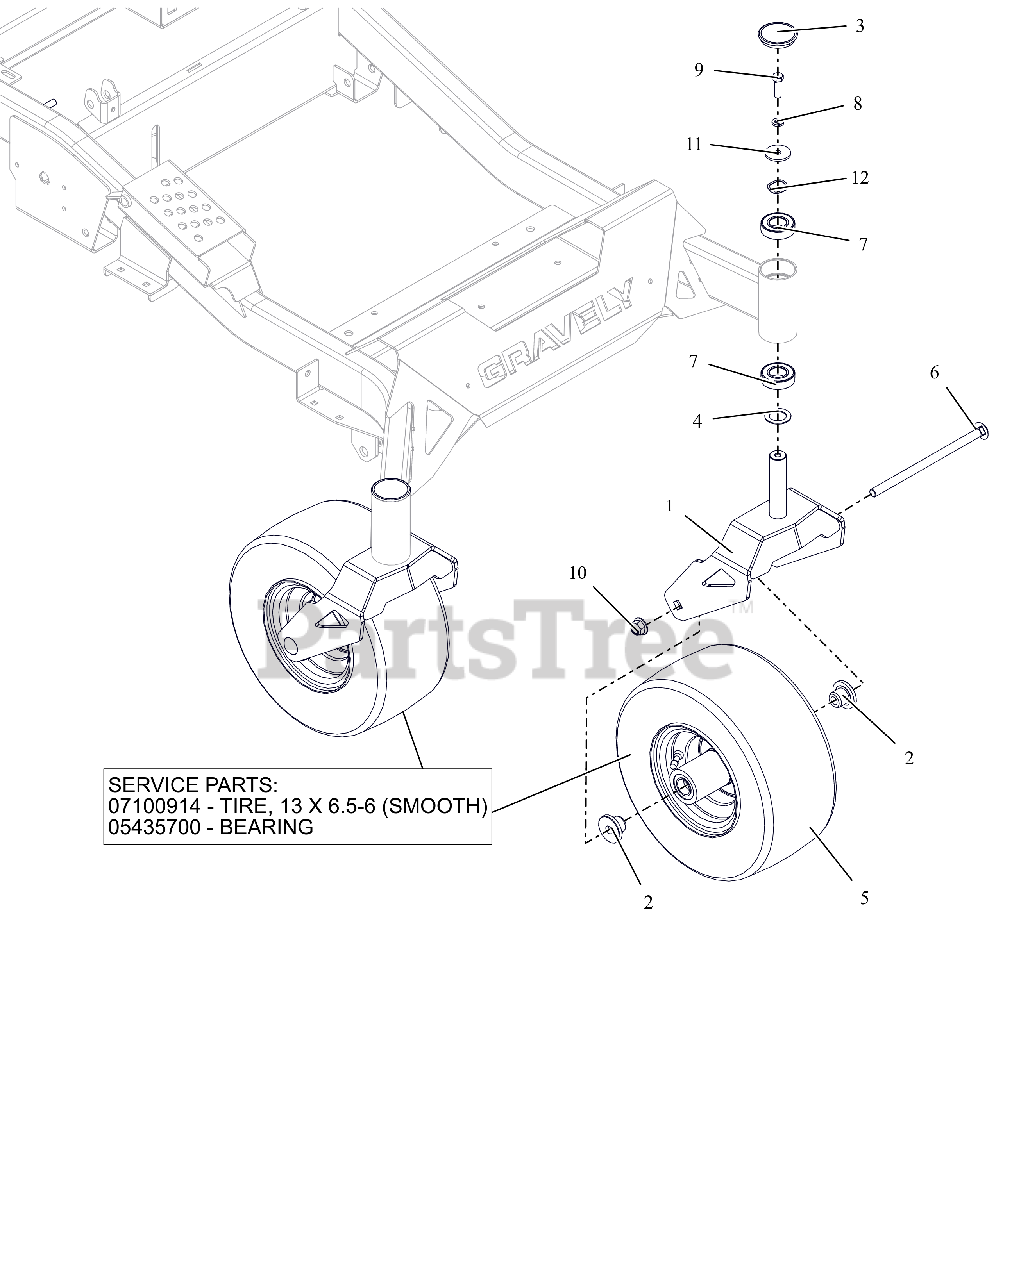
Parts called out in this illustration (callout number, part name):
1	WLDMT, HD CASTER FORK
2	SPACER, FRONT WHEEL
3	CAP, DUST
4	WSHR-HRD-THRS 1.007X1.542X.062
5	ASM, WHL/TIRE 13X6.50-6
5	TIRE, 13X6.50-6 SMOOTH
5	BRG, 25MM ID X 52MM OD X 15MM
6	BTL,RHSN .500-13 X 9 G5 ZCC
7	BRG,BALL 1.00X2.00X.563(1641)
8	WSHR, LK-HVY .375X.115 ZCC
9	BLT, HEX .38-16X1.25 G5 ZCC
10	NUT,NYL-FLG .50-13 GF ZCC
11	WSHR, FLT .380X1.50X.125 ZCC
12	WSHR-WAVE 1.0X1.25X.028 .145FH
